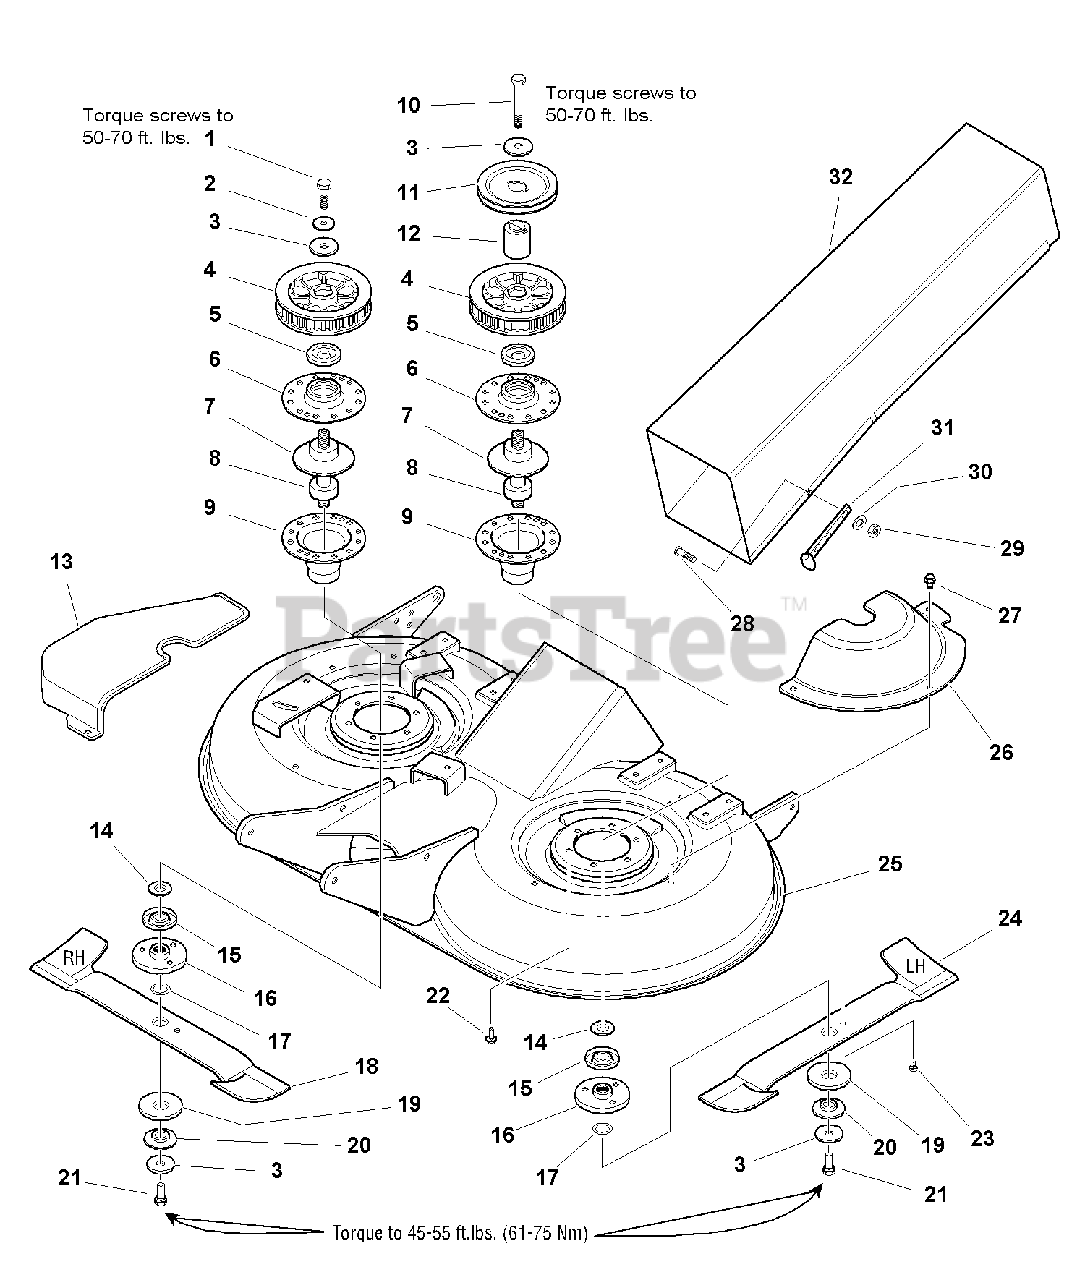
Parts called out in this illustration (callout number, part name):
1	CAPSCREW, Hex Head, 7/16-14 x 1-3/4 G8
2	WASHER, 7/16
3	WASHER, Spring, 1-3/4
4	SPROCKET & FLANGE ASSEMBLY, Rivited
5	SHIELD, Bearing Upper, Arbor
6	HOUSING, Arbor Top
7	GASKET, Foam
8	ARBOR SHAFT & BEARINGS ASSEMBLY
9	HOUSING, Arbor Bottom w/Lube Fitting
10	CAPSCREW, Hex Head, 7/16-14 x 3-1/2 G8
13	COVER, Arbor R H
14	WASHER, Shim
15	SHIELD, Bearing, Mower Arbor Lower
16	ADAPTER, Blade 26, 30, 36, 42 & 48"
18	BLADE, Mower RH 40
20	WASHER, Spline
21	CAPSCREW, Hex Head, 7/16-14 x 1-1/4 G8
22	CAPSCREW, Hex Washer Head, Taptite, 5/16-18 x 3/4
24	BLADE, Mower LH 40
25	HOUSING ASSEMBLY, 40" Mower, 2 Spindle, Orange
25	HOUSING ASSEMBLY, 40" Mower, 2 Spindle, Red
26	COVER, Arbor LH
27	CAPSCREW, Hex Washer Head, Taptite, 5/16-18 x 1/2
28	CAPSCREW, Truss Head, Phillips, #10-24 x 3/4
29	NUT, Hex Nylock , 10-24
30	WASHER, 3/16
31	STRAP, Hood, Black Rubber, 4.8" Long
32	TUBE ASSEMBLY, Top & Bottom Rear
